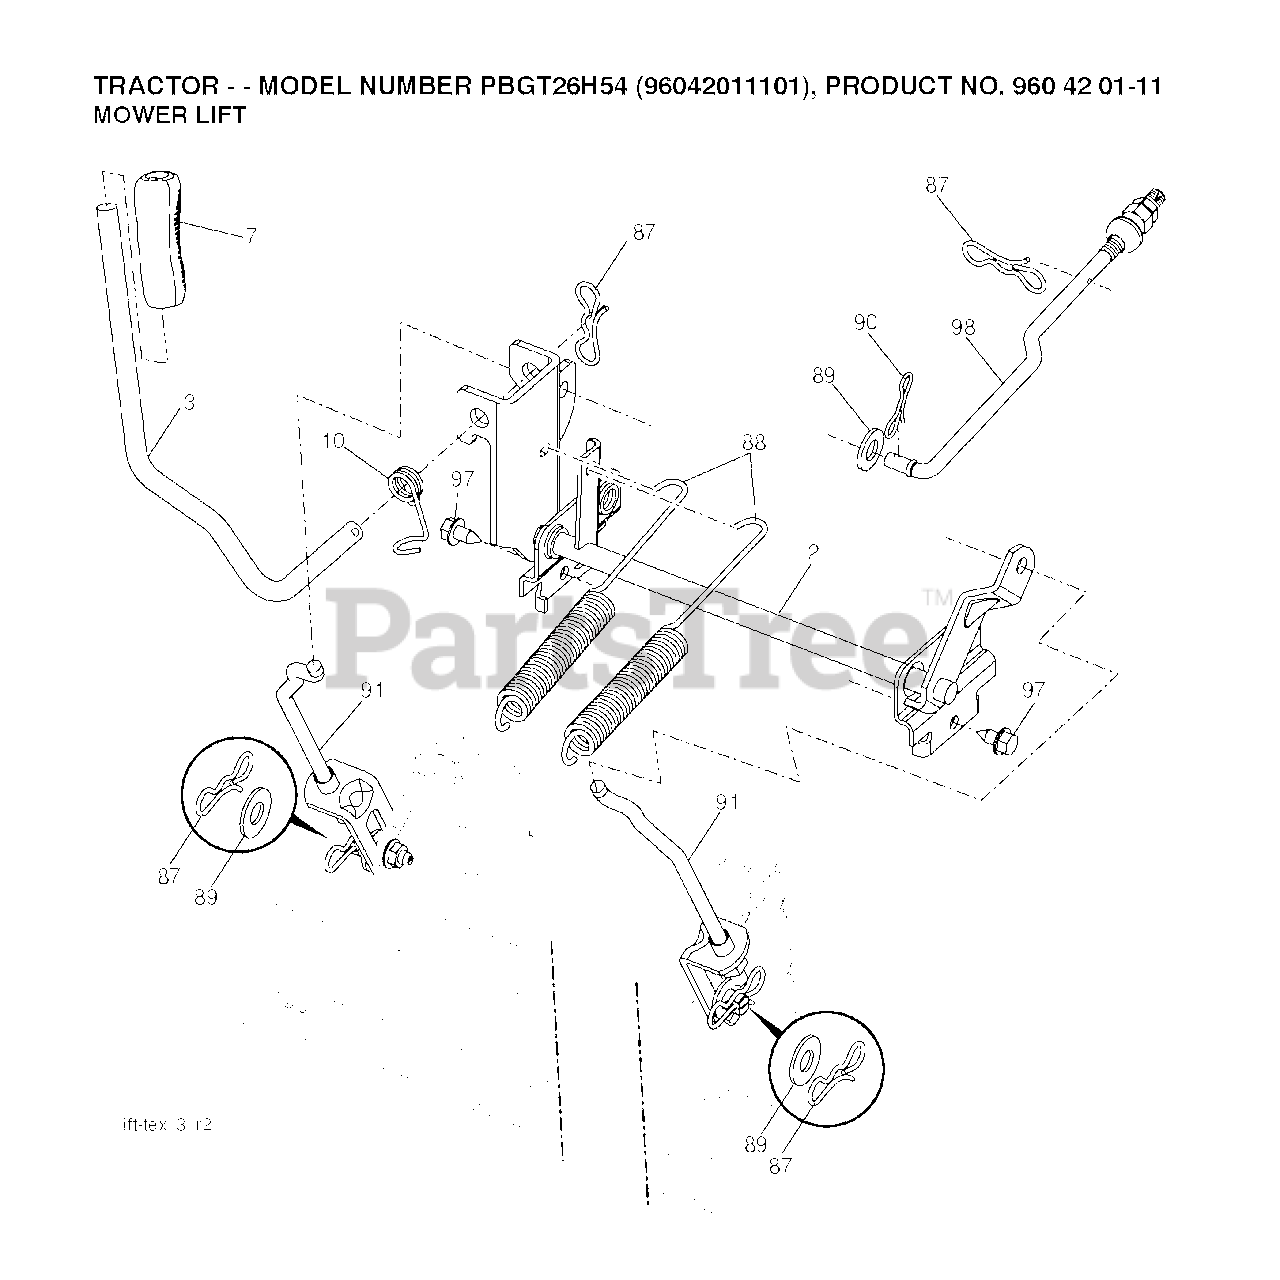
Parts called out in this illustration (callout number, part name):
2	SHAFT.ASM.CROSS.LIFT
3	LEVER.LIFT.HANDLE.GT
7	GRIP.HANDLE.LIFT.PVC.BLACK
10	SPRING.TORSION.LIFT.HANDLE
87	PIN.COTTER.7/16.BOW TI.
88	SPRING.LIFT.ASSIST.GT2
89	WASHER.CLEAR.ZINC
90	PIN.COTTER.5/16.BOW TI
91	LINK.ASM.LIFT.54"TG
97	SCREW, 3/8-16X3/4
98	LINK.ASM.SUSP.FRONT.MWR.10.5
